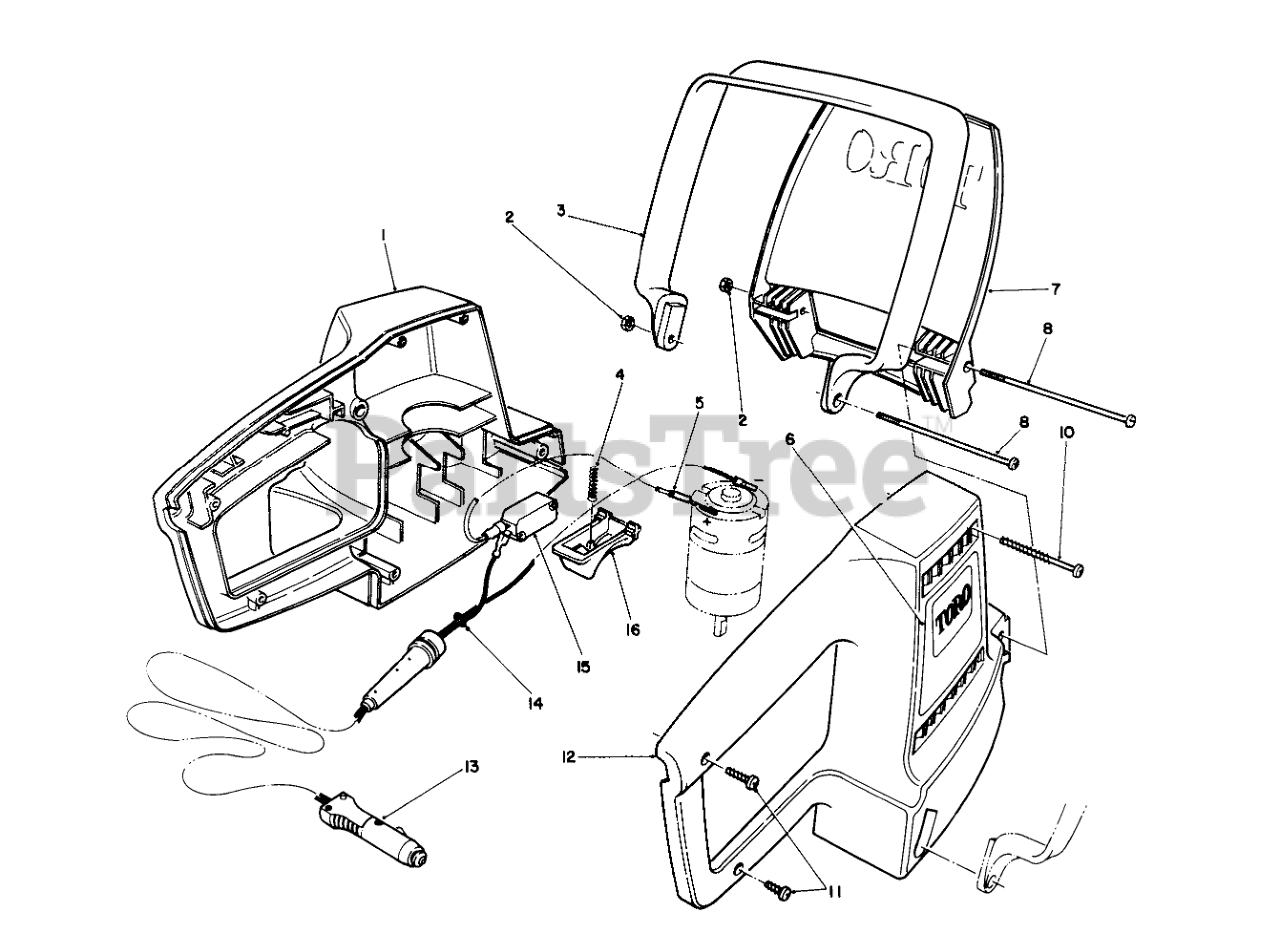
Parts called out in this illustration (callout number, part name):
1	Housing-Handle, L.H.
2	NUT-HJ
3	ASSIST HANDLE
4	SPRING-TRIGGER
5	WIRE ASSEMBLY
6	DECAL-HEDGE, RT
7	SHIELD
8	SCREW-PPH
10	SCREW - #8 X 2.0
11	SCREW-PPH
12	Housing-Handle, R.H.
13	CORD-HEDGE
14	Relief-Strain
15	SWITCH
16	TRIGGER
